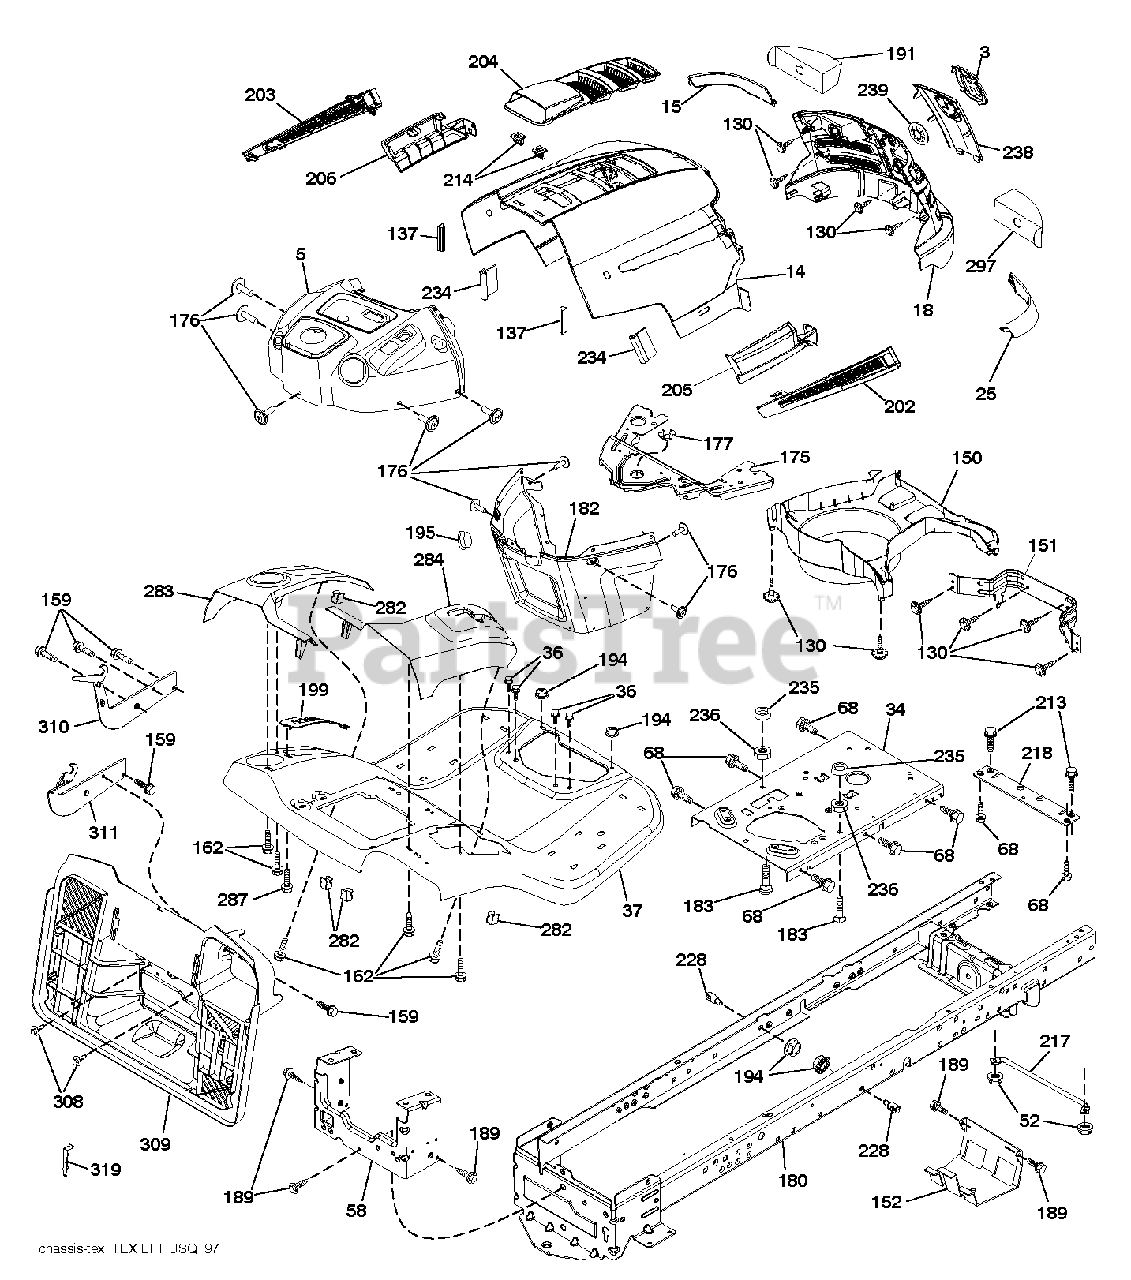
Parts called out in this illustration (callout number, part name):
3	RP LOGO
5	SUBASM.DASH.UPPER.W/BUMPER
14	HOOD.HUSQVARNA.LT.ORANGE
15	LENS.HUSQVARNA LT.RH
18	GRILLE.SVC.HUSQVARNA.GREY
25	LENS.HUSQVARNA LT.RH
34	PLATE.ENGINE.WELDED.CHASSIS
36	SCREW 5/16"
37	FENDER.TEX.SRD.CRD.BASE
52	LOCKNUT
58	DRAWBAR UPPER 2PC SMALL FENDER
68	DASH LOWER
130	SCREW.#10 X 0.750.BOS
137	BUMPER DASH
150	ROD.PIVOT.HOOD
151	BRACKET PIVOT
152	SHIELD.BROWNING.W/TEX
159	SCREW, 3/8-16X3/4
162	SCREW.HI-LO.CONSOLE
175	CROSSMEMBER
176	SCREW.#10-24X5/8.RN.QU
177	BUSHING STEERING
180	CHASSIS.WLDMNT.14GA.2PC.18".TI
182	DASH.LOWER.PREDATOR LT
183	BOLT.5/16-18X1-1/4 FULL THD
189	SCREW
191	INSERT.REFLECTIVE.RH.
194	NUT LOCK HEX FLANGE 5/16-18
195	PLUG.TEX.DASH.SVC.MINDER.GREY
199	PLATE DECK LIFT
202	VENT.SIDE.HUSQVARNA.LT.RT
203	VENT.SIDE.HUSQVARNA.LT.LFT
204	SUBASM.TOP.VENT.HUSQ.LT
205	SKIRT.SIDE.HUSQVARNA.LT.RT
206	SKIRT.SIDE.HUSQVARNA.LT.LEFT
213	BOLT
214	CLIP.RETAINER.TINNER.
217	ROD.PIVOT.HOOD
218	X-PIECE.HOOD.STOP.NON/
228	STUD.FASTNER.W/ANTI-ROTATE
234	BUMPER.HOOD.TEX.HUSQVARNA
235	SPACER FENDER
236	NUT.CENTERLOCK.5/16-
238	TRIM.HUSQ LT.668
282	CLIP.RETAINER.CONSOLE.LT.HUSQ
283	CONSL.DECKLIFT.LH.SRD.TEX.CRD
284	CONSL.SHIFT.GEAR.RH.SRD.GREY
287	SCREW 1/4X20
297	INSERT REFLECTIVE
308	BOLT, 5/16-18 X 1 3/4
309	BACKPLATE.BAGGER.V2.SRD
